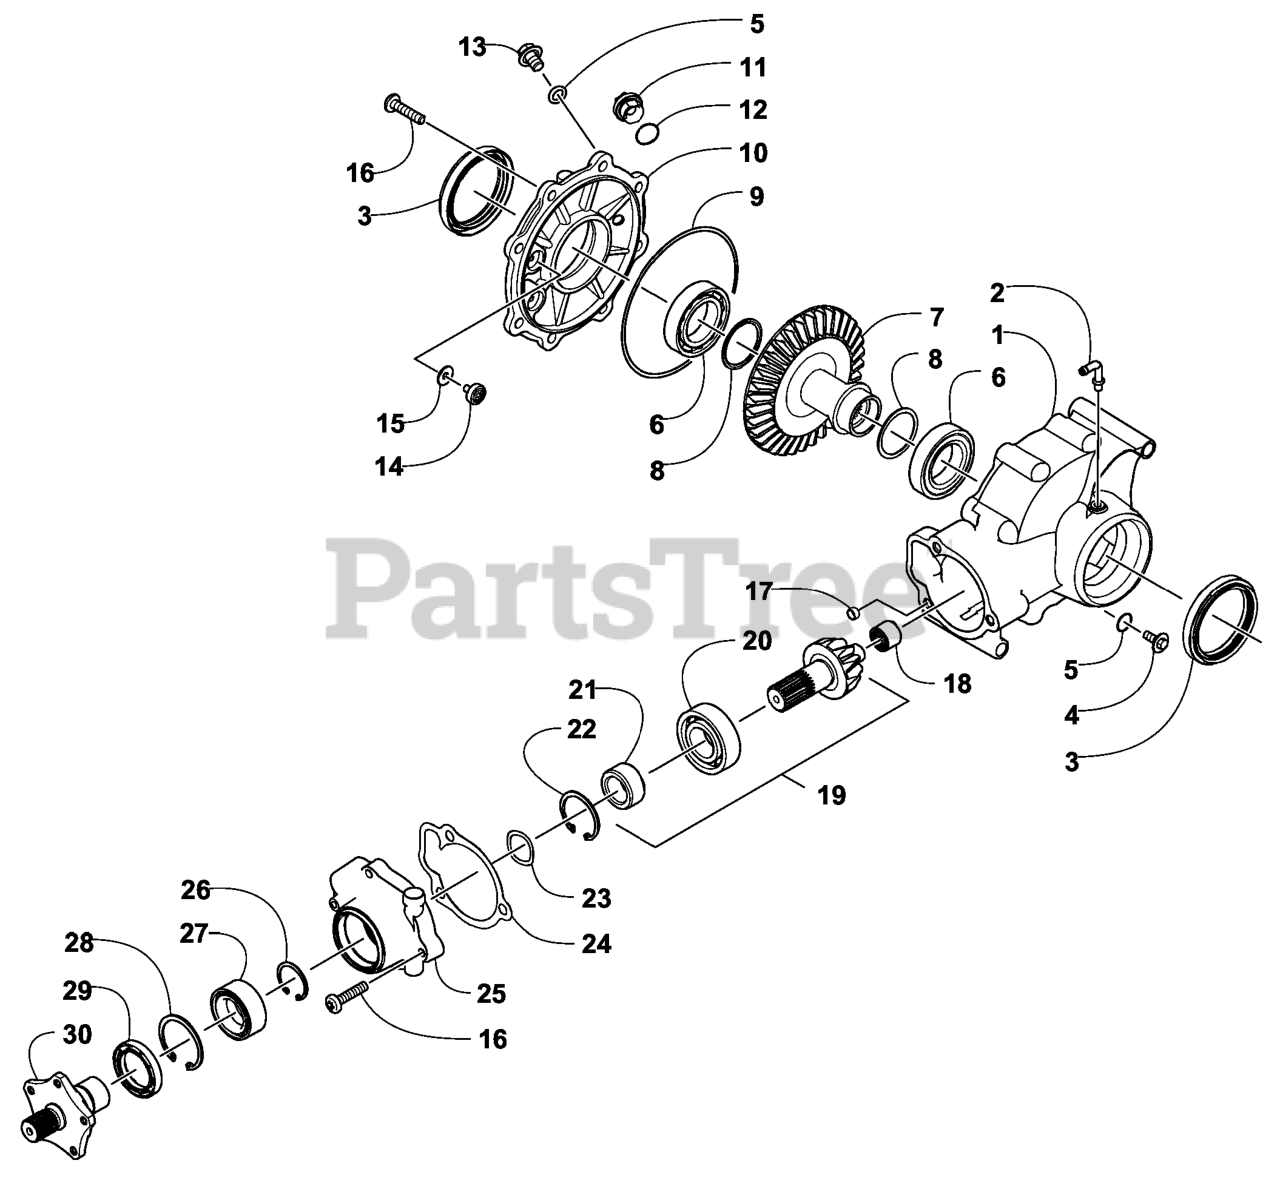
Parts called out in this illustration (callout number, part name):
1	HOUSING-GEARCASE, REAR
2	FITTING-BARB, 90 DEG
4	PLUG-DRAIN, MAGNETIC
6	BEARING-BALL
7	GEAR-REAR, 36T)
10	COVER-GEARCASE, REAR
11	PLUG-FILL
13	PLUG-OIL LEVEL
14	BUTTON-THRUST
16	SCREW-TSPNH, SELF TAP
17	PIN-DOWEL
18	BEARING-NEEDLE
19	GEARPINION, 10T
20	BEARING-BALL
21	COLLAR-RETAINING
22	RING-RETAIN, INT
23	WASHER-SPRING
24	GASKET-FLANGE
25	ARM - IDLER
26	RING-RETAINING
27	BEARING-BALL
28	RING-RETAINING, INTERNAL
30	SHAFT-INPUT
